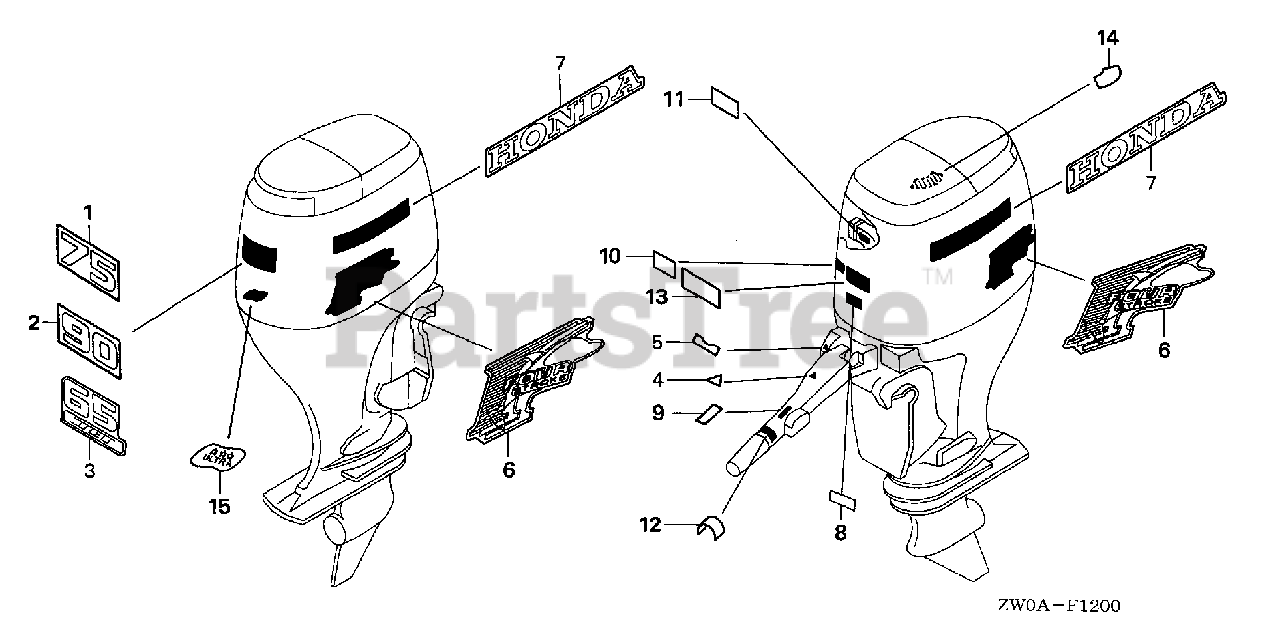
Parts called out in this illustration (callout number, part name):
3	MARK, RR. (BF65) (JET)
4	MARK, EMERGENCY SWITCH INDICATION (ENGLISH)
5	MARK, STARTER (ENGLISH)
6	MARK, SIDE
7	MARK, SIDE STRIPE
8	MARK (E-SPEC)
9	MARK, CHANGE (JAPANESE/ENGLISH)
11	LABEL, OIL CAUTION (ENGLISH)
12	MARK, THROTTLE (ENGLISH)
13	LABEL, CAUTION OPERATOR (ENGLISH)
14	MARK, EMERGENCY START (ENGLISH)
